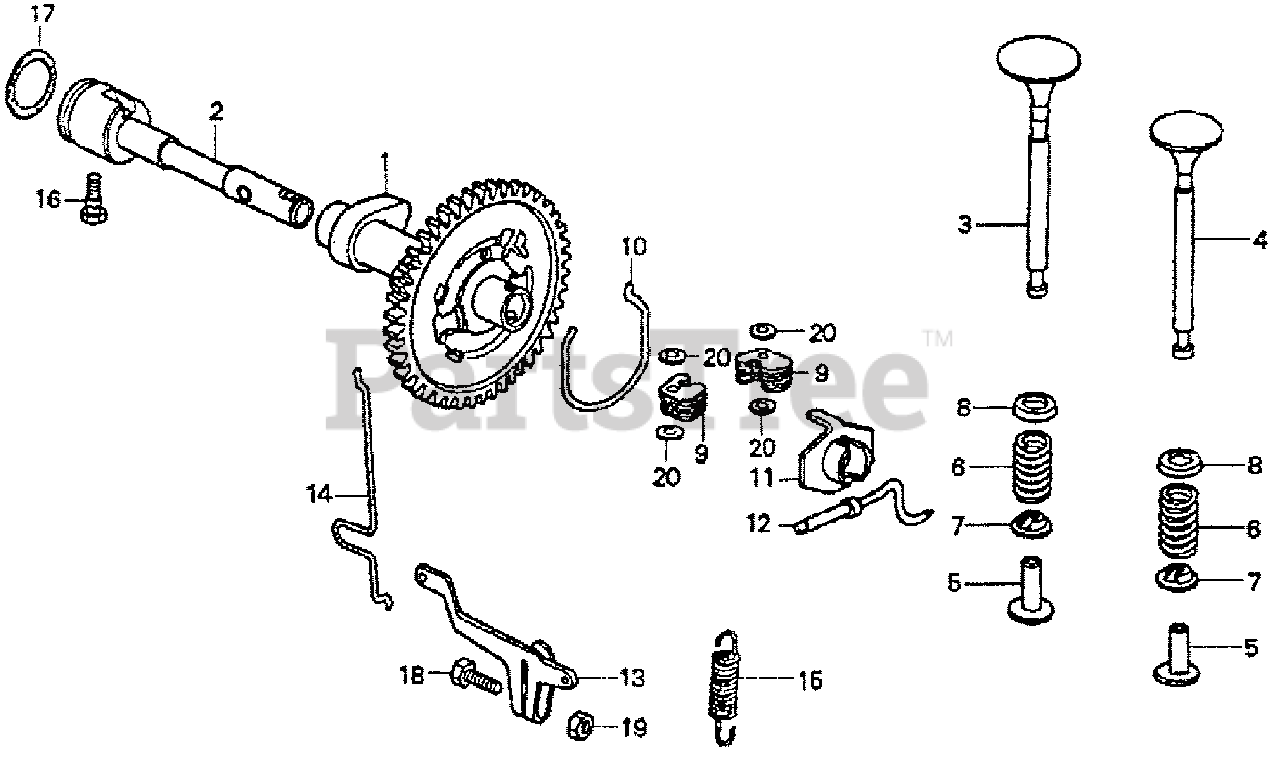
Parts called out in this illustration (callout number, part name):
2	CENTER, CAMSHAFT
3	VALVE, IN.
4	VALVE, EX. (NOT AVAILABLE)
5	LIFTER, VALVE
6	SPRING, VALVE (NOT AVAILABLE)
7	RETAINER, VALVE SPRING
8	SEAT, SPRING (NOT AVAILABLE)
9	WEIGHT, GOVERNOR
10	CENTER, GOVERNOR WEIGHT
11	SLIDER, GOVERNOR
12	SHAFT, GOVERNOR ARM (NOT AVAILABLE)
13	ARM, GOVERNOR
13	ARM, GOVERNOR (NOT AVAILABLE)
14	ROD, GOVERNOR (NOT AVAILABLE)
15	SPRING, GOVERNOR
16	BOLT, CAMSHAFT CENTER STOPPER
17	O-RING (23.5X2.1) (ARAI)
18	BOLT, HEX. (6X16)
19	NUT, HEX. (6MM)
20	WASHER, PLAIN (3MM)
